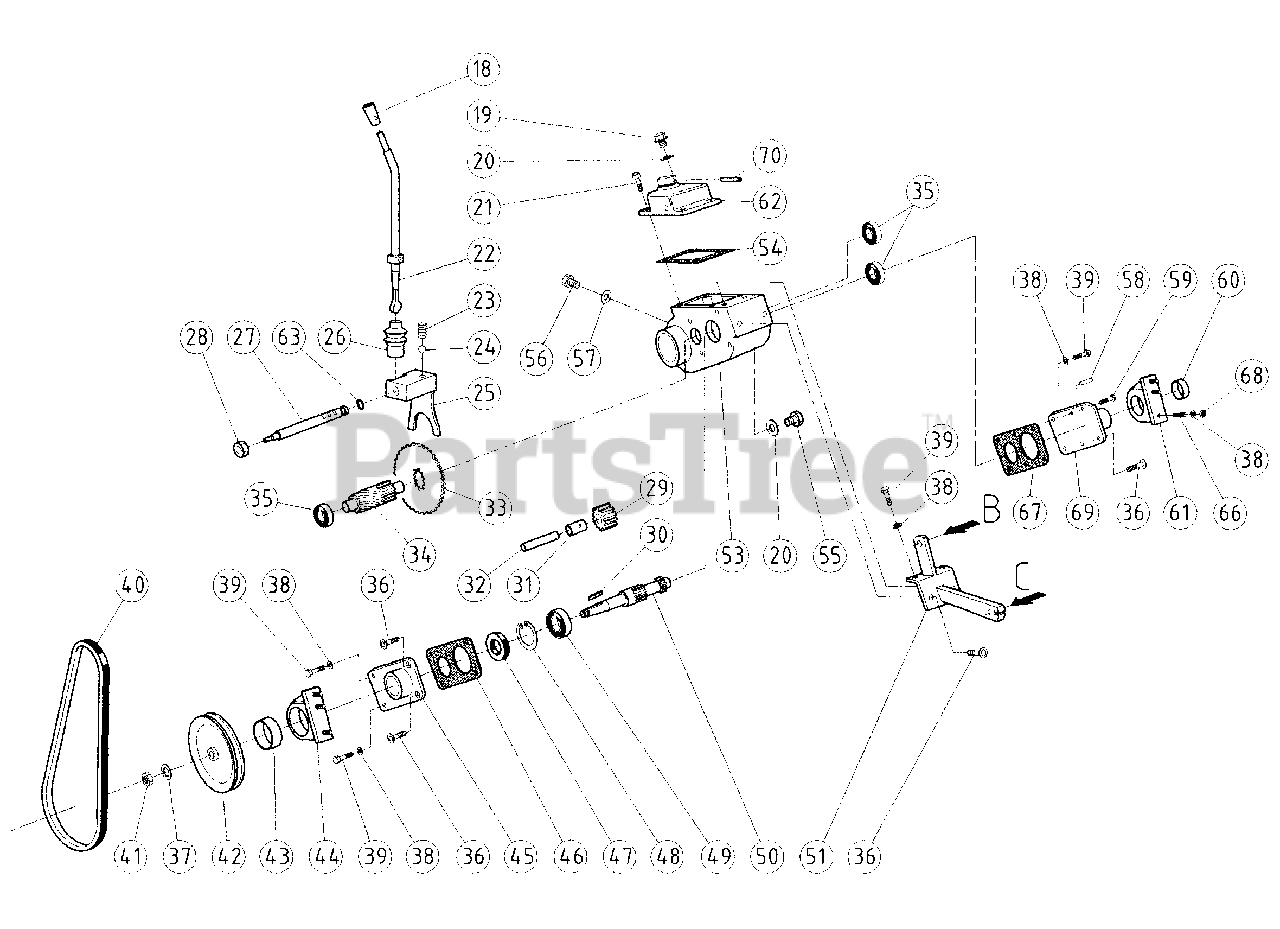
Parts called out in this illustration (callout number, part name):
18	Plastic knob Ø 12
19	Cap Plastic
20	Washer Fiber
21	Screw Allen M 8 x 16
22	Lever Engage-disengage
23	Spring Gear Fork 6x25
25	Fork 1st-2nd
27	Fork pivot
28	Nut Lock M8
30	Key 5x5x18
31	Gear 2nd Speed
33	Gear lst and 2nd
34	Gear Reduction-pinion
35	Bearing 15x35x11 6202-2RS
36	Screwcap M8x18
37	Washer Flat M12x24
38	Washer Wave M8
39	Screwcap M8x20
40	Belt Big 48-430 L443
42	Pulley Cast iron prim. Ø= 150 mm.
43	Bushing Self-lubricating
44	Support Box (righthand)
45	Cover (righthand)
46	Gasket Cover (righthand)
47	O-ring 17x40x7
48	Ring Snap Internal 140
49	Bearing 17x40x14 62203 2RS1
50	Pinion Primary
51	Support Tie Rod
54	Gasket Cover
55	Cap Metal
56	Button M6x8
57	Washer fiber M6x10
58	Pin Cylindrical 8x18
59	Screw Button Head M8x16
60	Bushing Self-lubricating PCM 252820 B
61	Support Box (lefthand)
62	Cover Box
63	O-ring 108 (8.73 x 1.78)
66	Screw Stud M8 UNI 5911
67	Gasket Cover (lefthand)
68	Nut 8 H6.5
69	Cover Left
70	Pin Cylindrical 6x35
71	Roller Cage Bearing HK 1412
